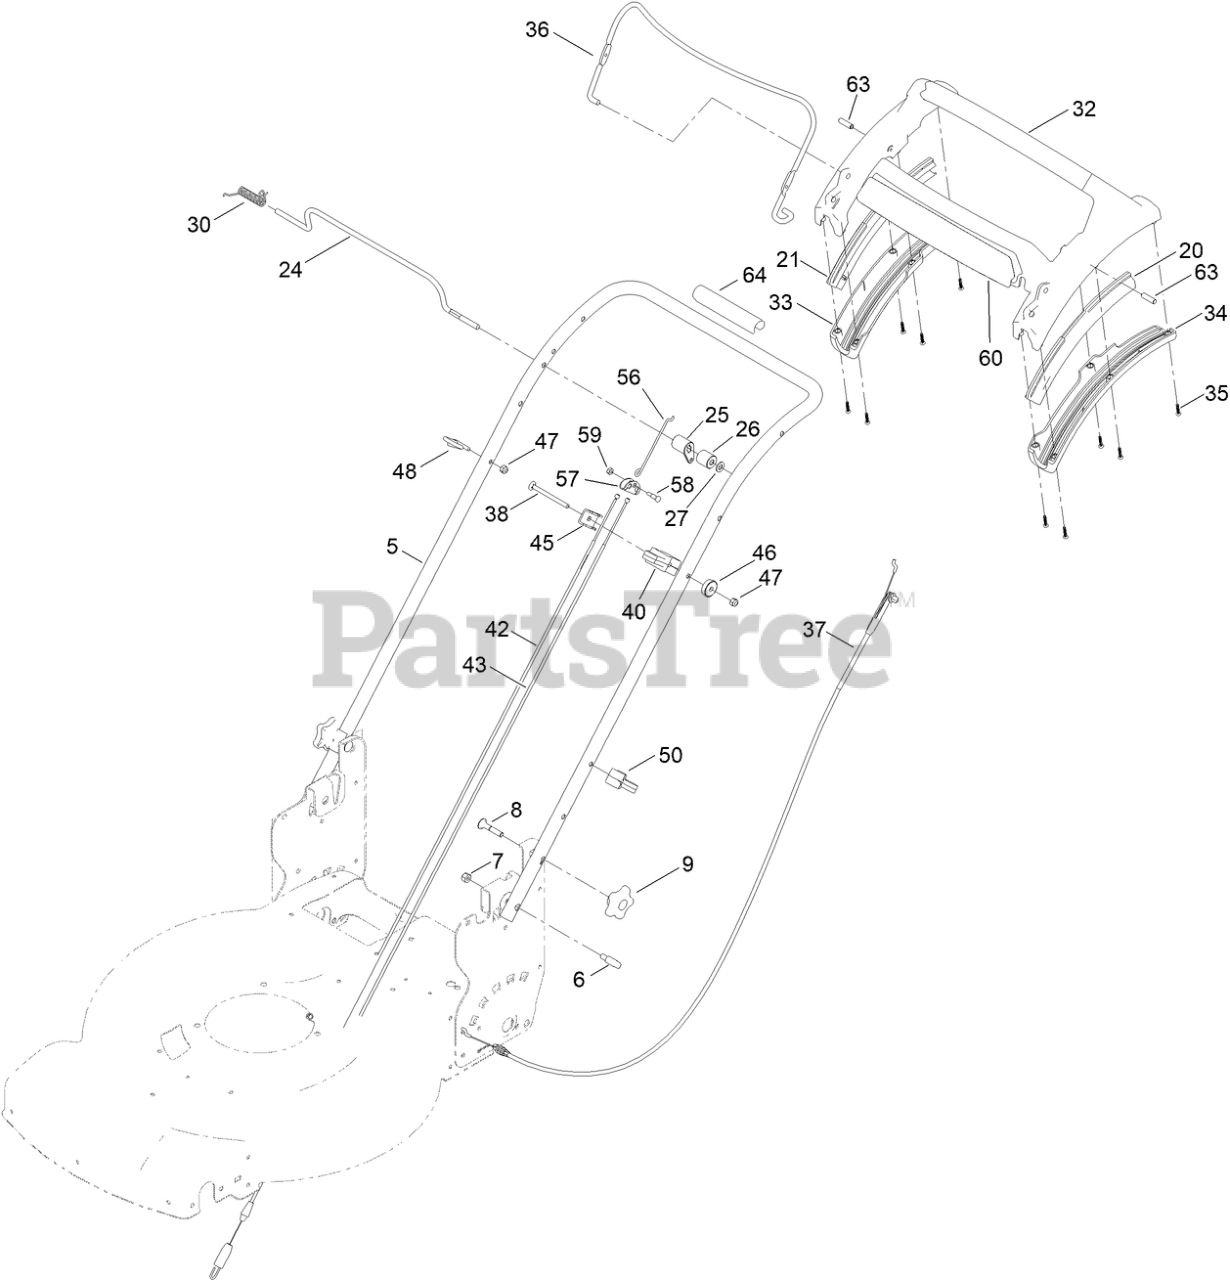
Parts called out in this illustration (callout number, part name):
5	HANDLE-CURVED, AWD
6	BOLT-SHOULDER, HANDLE
7	NUT-LOCK, NI
8	SCREW-CARR
9	KNOB-HANDLE
20	GUIDE-CURVED, LH (RWD)
21	GUIDE-CURVED, RH (RWD)
24	ROD-CONTROL, TRACTION
25	LEVER-TRACTION, AWD
26	SPACER-LEVER, TRACTION
27	WASHER-PLAIN
30	SPRING-TORSION
32	HANDLE-PERSONAL PACE, CURVED
33	BOTTOM-HANDLE, RH
34	BOTTOM-HANDLE, LH
35	SCREW-PPH
36	BAIL-BRAKE
37	CABLE-BRAKE, PP BS
38	SCREW-CARR
40	ANCHOR-CABLE, AWD
42	CABLE-TRACTION, FRONT (AWD)
43	CABLE-TRACTION, REAR (AWD)
45	CLAMP-CABLE
46	WASHER-CURVED
47	NUT-LOCK, NI
48	GUIDE-ROPE
50	GUIDE-CABLE
56	LINKAGE-EQUALIZER
57	YOKE-CABLE
58	BOLT-EQUALIZER
59	NUT-LOCK, NI
63	PIN-HANDLE, PP
64	HANDLE-COVER
